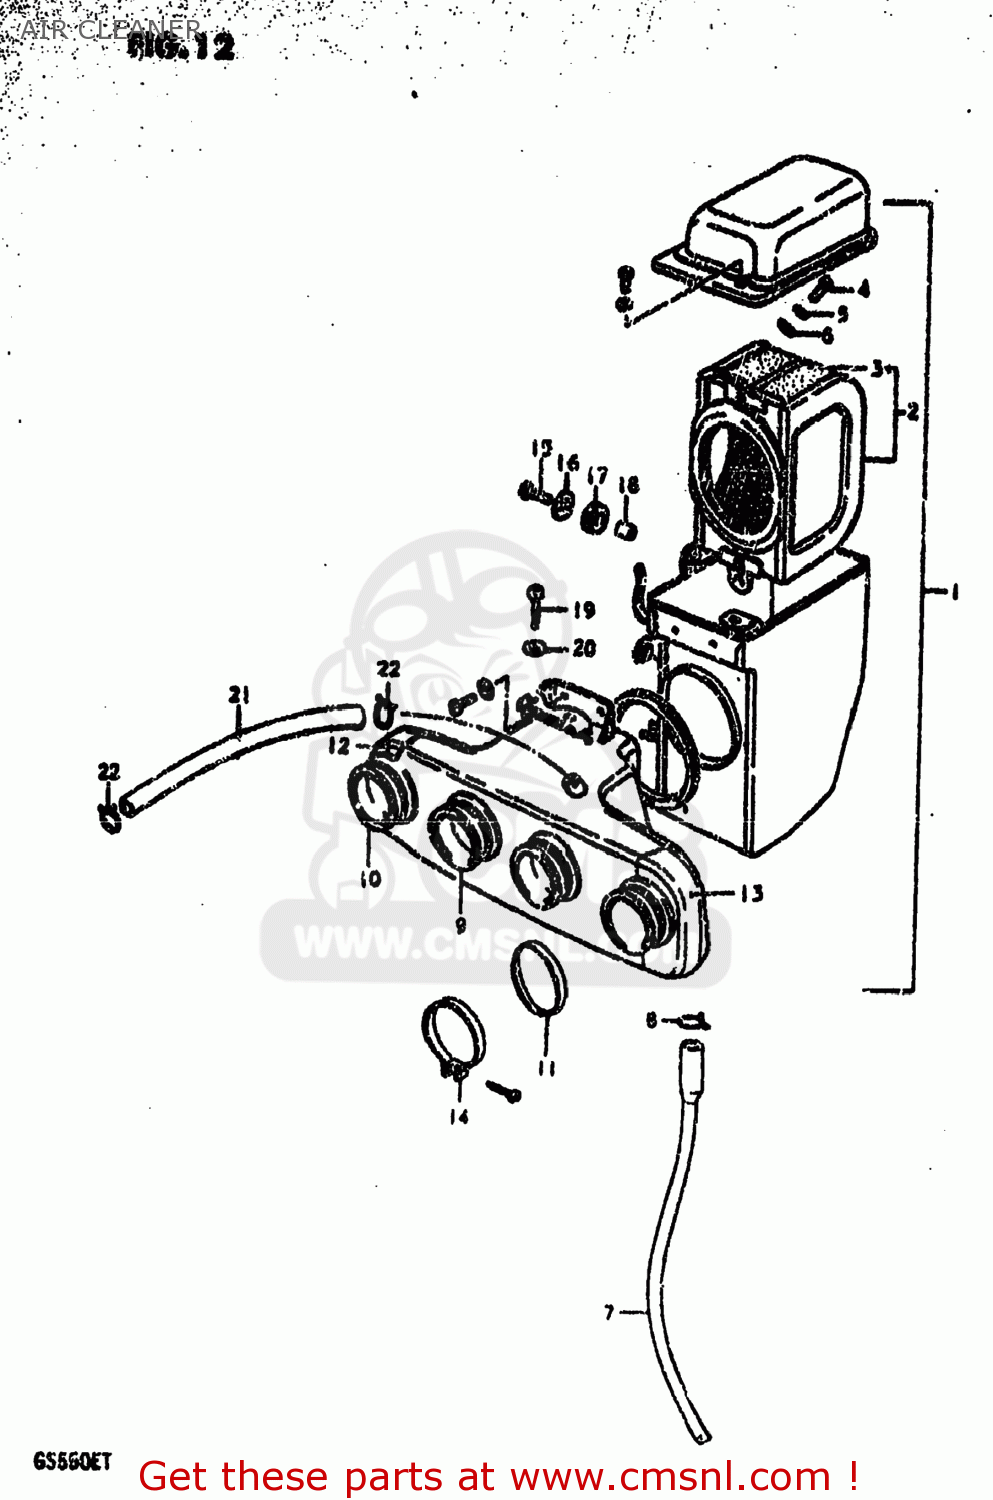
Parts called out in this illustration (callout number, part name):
1	CLEANER ASSEMBLY,AIR
2	FILTER ASSY
3	FILTER
4	SCREW
5	LOCK WASHER
6	WASHER
7	HOLDER,FILTER
8	CLIP
9	TUBE,AIR CLEANER OUTLET A
10	TUBE,AIR CLEANER OUTLET B
11	RING,CARBURETOR AIR INLET HOSE
12	COVER,AIR CLEANER,RIGHT
13	COVER,AIR CLEANER,LEFT
14	CLAMP
15	BOLT
16	WASHER
17	CUSHION
18	SPACER (6.1X9X9)
19	SCREW 6X12
20	WASHER
21	HOSE
22	CLIP
